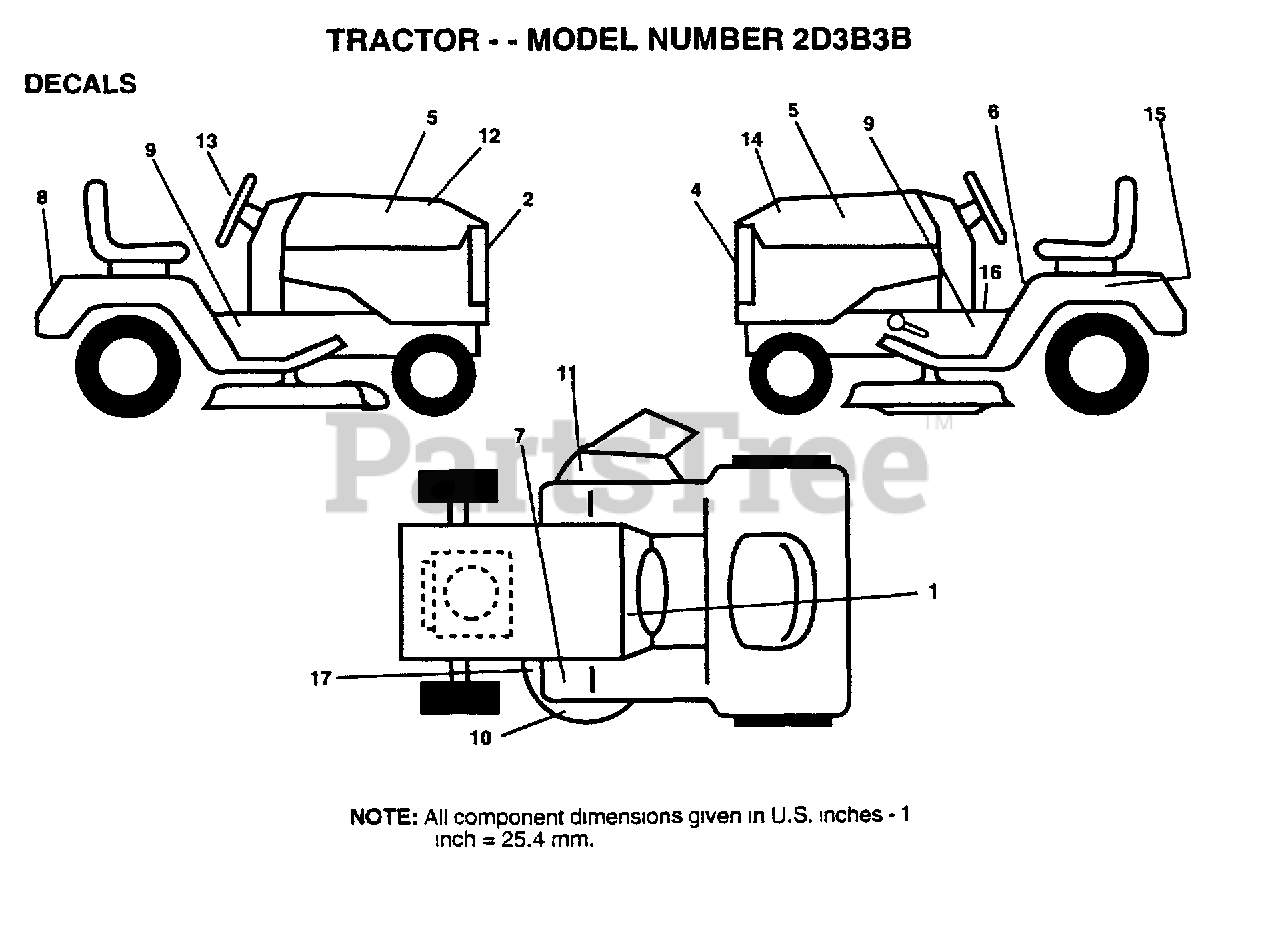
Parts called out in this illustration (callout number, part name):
1	DECAL.DASH.INSTR.
2	GRILL DECAL
5	DECAL.HOOD.INSERT
6	DECAL CAUTION
7	DECAL T
8	FENDER DECAL
11	"DECAL, WARNING"
12	DECAL HOOD RH RLY
13	"DECAL,STR WHL"
14	DECAL HOOD LH RLY
15	DECAL
16	DECAL BRAK PARK
17	DECAL
